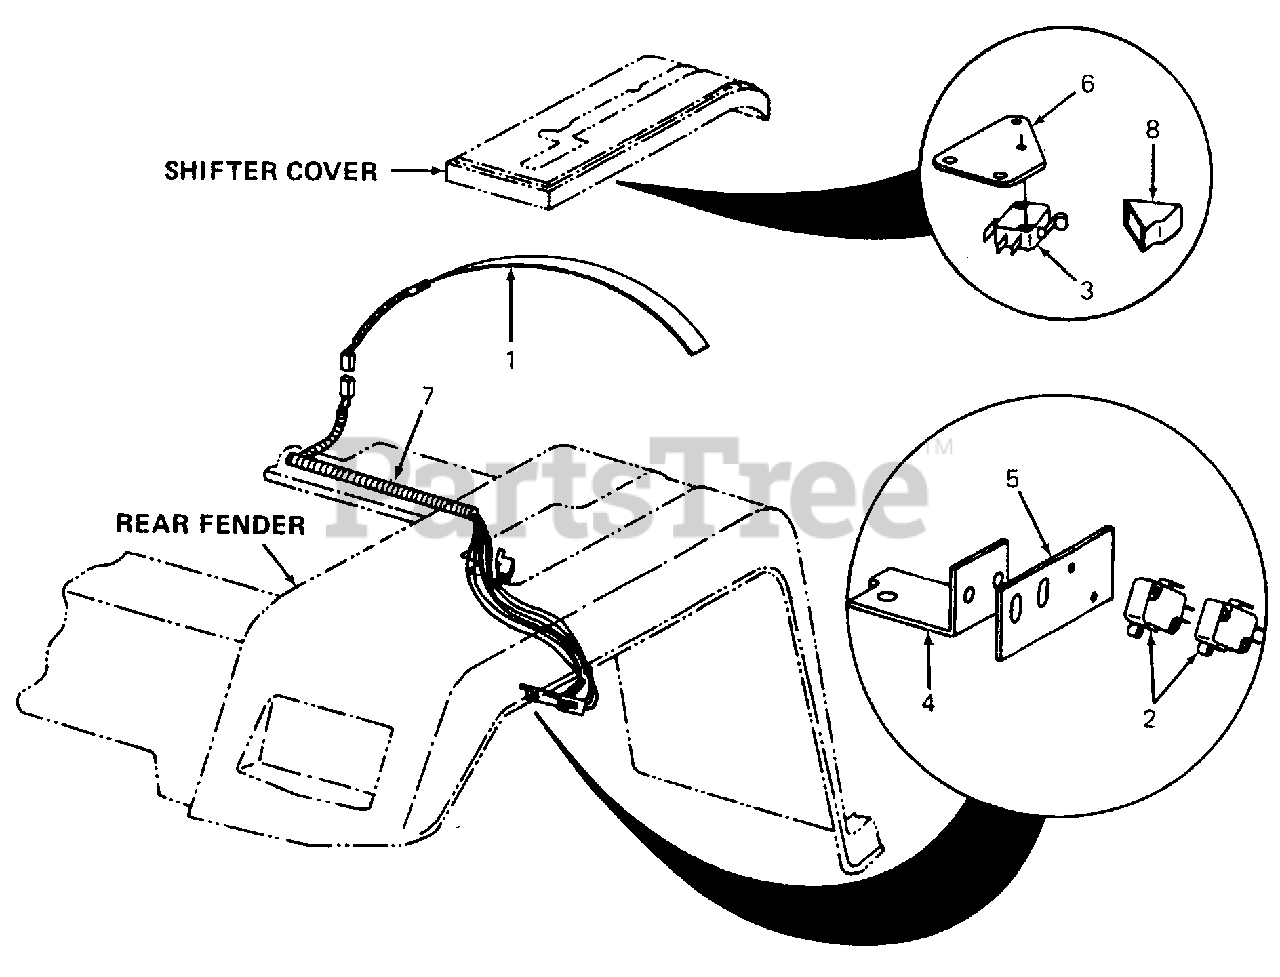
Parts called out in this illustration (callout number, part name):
1	Switch, Seat
2	Switch, Transmission Shift Lever
3	Switch, Shift Cover
4	Bracket, Switch Mounting
5	Plate, Switch
6	Plate, Shift Cover Switch
7	Harness, Main Wiring
8	Cover, Switch
